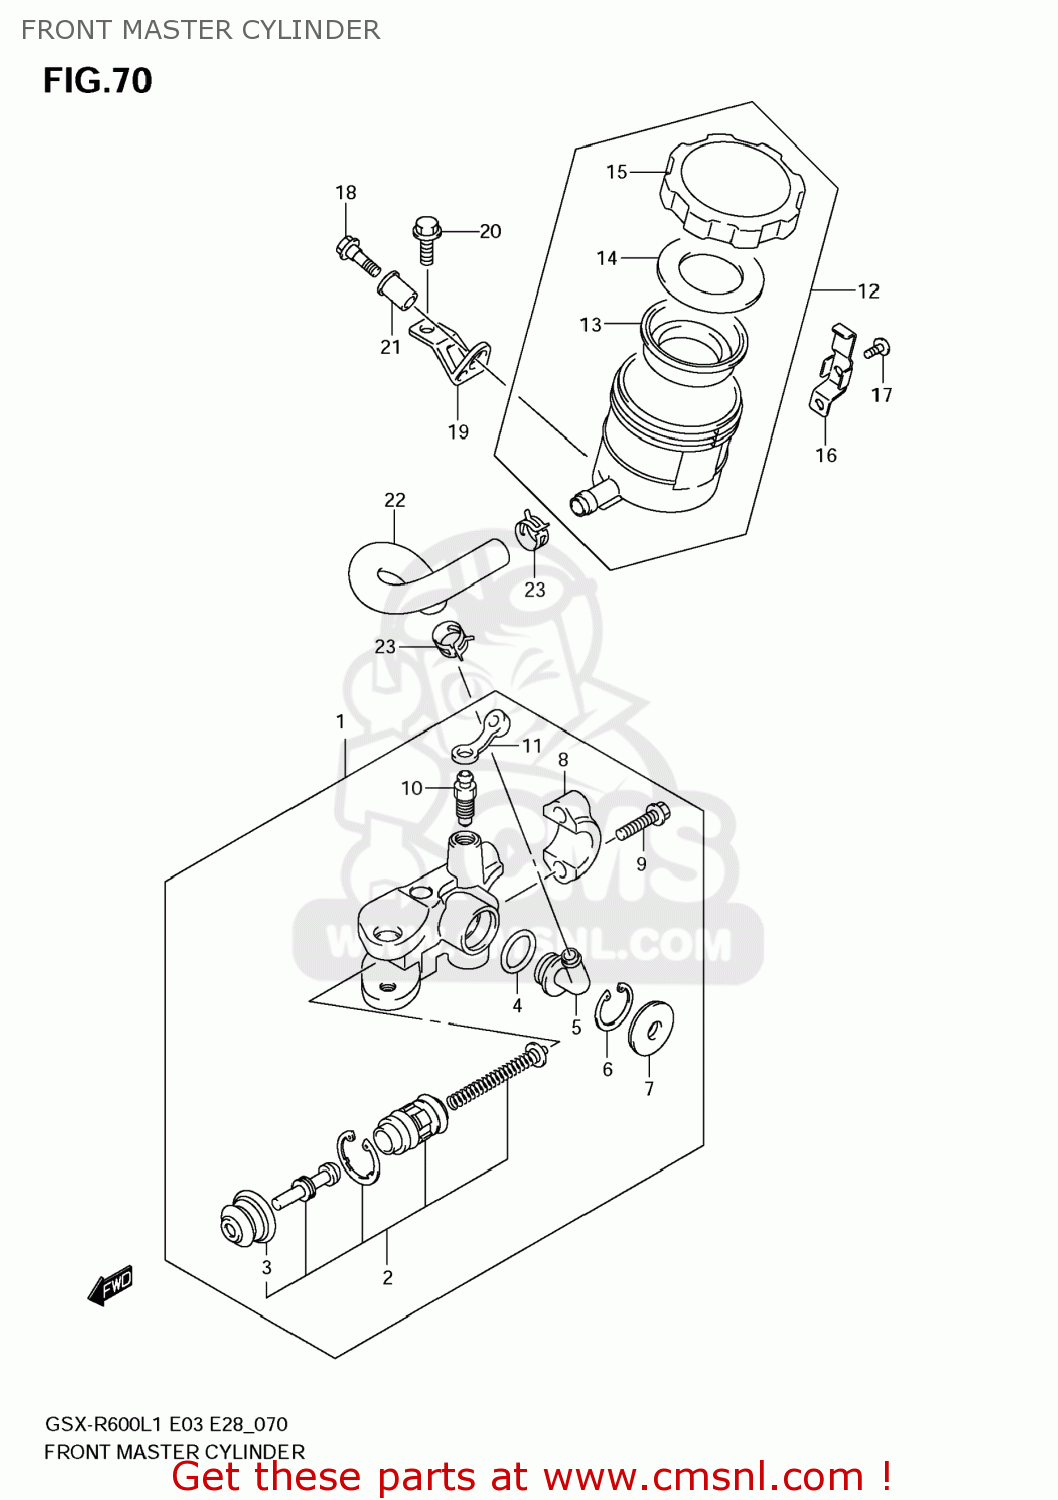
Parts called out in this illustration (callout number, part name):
1	CYLINDER ASSY,
2	PISTON & CUP S
3	BOOT
4	O RING
5	CONNECTOR
6	CIRCLIP
7	COVER,DUST
8	HOLDER
9	BOLT(6X22)
10	BLEEDER
11	CAP,BLEEDER
12	TANK ASSY,RESERVOIR
13	DIAPHRAGM
14	PLATE,DIAPHRAGM
15	CAP
16	PLATE,RESERVOIR TANK CAP
17	SCREW
18	BOLT(5X17)
19	BRACKET,FR RES
20	BOLT
21	NUT
22	HOSE,FRONT RES
23	CLAMP,RESERVOIR TANK FR
